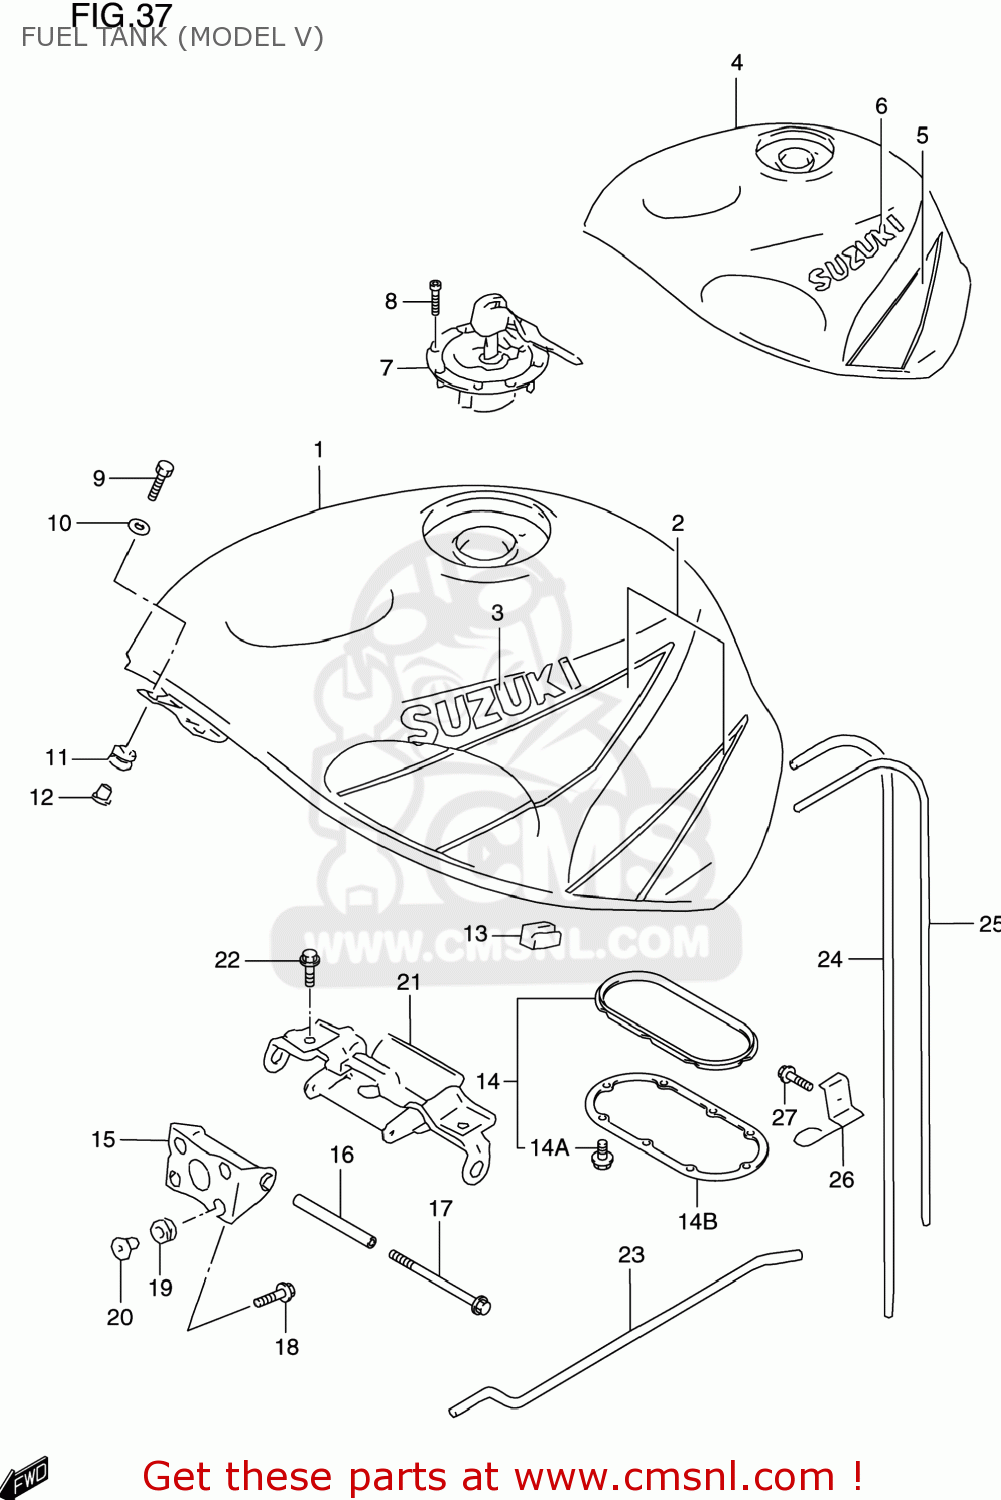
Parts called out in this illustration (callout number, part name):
1	TANK ASSEMBLY,FUEL
2	TAPE SET,FUEL TANK
3	EMBLEM,FUEL TANK
4	TANK ASSEMBLY,FUEL
5	TAPE SET,FUEL TANK
6	EMBLEM,FUEL TANK
7	CAP SET,FUEL TANK
8	BOLT(5X20)
9	SCREW(6X25)
10	WASHER
11	CUSHION
12	WASHER
13	CUSHION,FUEL TANK SIDE
14	PACKING SET,FUEL PUMP (NAS)
14A	BOLT,FUEL PUMP
14B	PLATE,FUEL PUMP GASKET
15	BRACKET COMP,FUEL TANK
16	SPACER,FUEL TANK RR
17	BOLT
18	BOLT 6X20,WITH PLAIN WASHER
19	CUSHION
20	WASHER
21	BRACKET,FUEL TANK NO.2
22	BOLT
23	STAY,FUEL TANK
24	HOSE(5X8.2X600)
25	HOSE(7X10.2X600)
26	GUIDE COMP,DRAIN HOSE
27	BOLT
